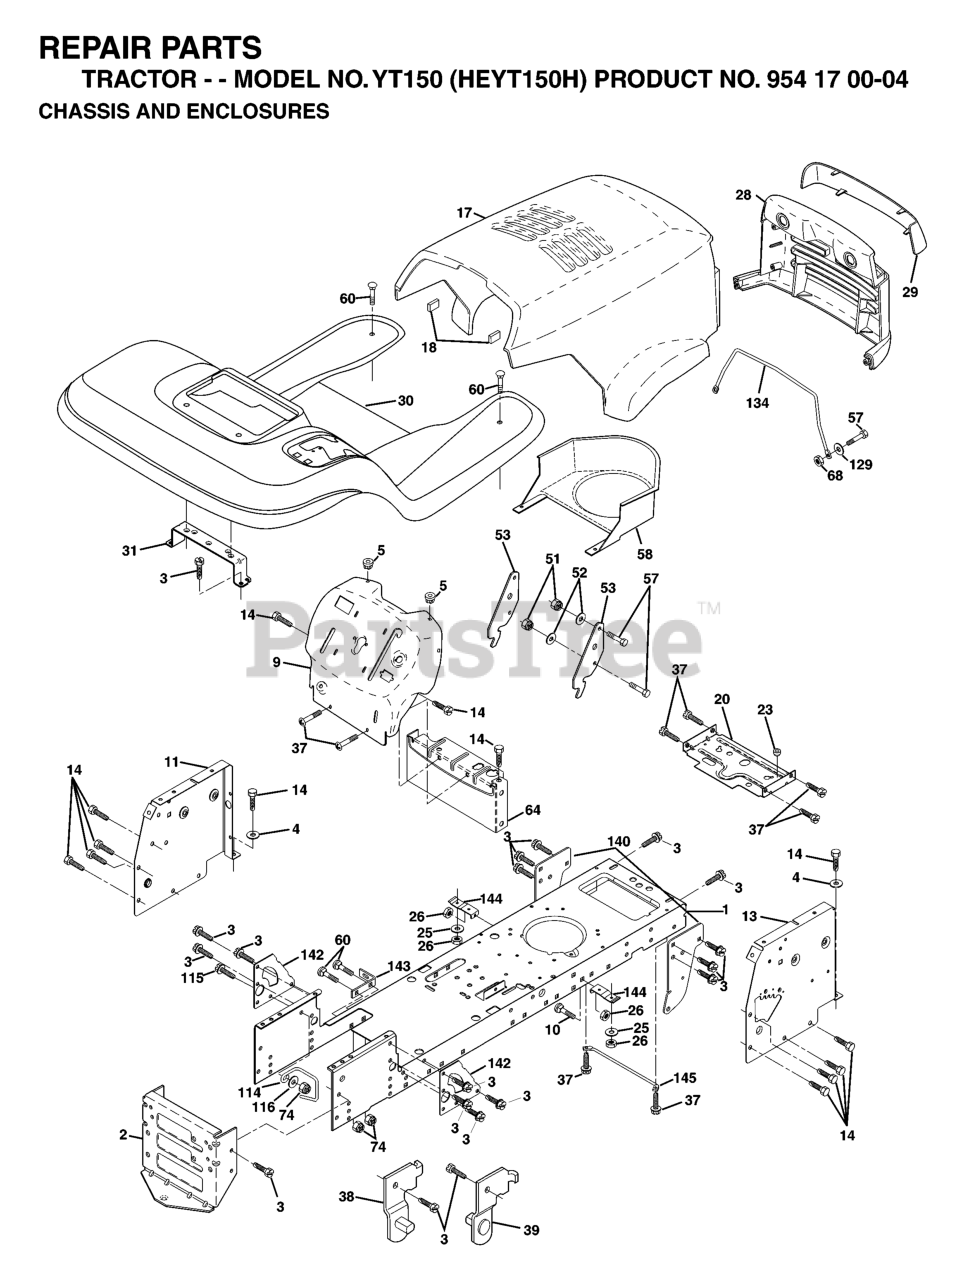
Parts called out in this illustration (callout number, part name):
2	STRETCH DRAWBAR
3	SCREW
4	Washer 13/32 X 3/4 X 16 Ga.
5	BUMPER.RUBBER.HOOD
10	BOLT D
11	PANEL DASH LH
13	DASH PANEL
17	HOOD - LT/YT
18	BUMPER HOOD T
20	PLATE MTG
23	BUSHING.SNAP.NYL.BLK.
25	WASHER
26	NUT
28	GRILLE LT/PL HUSQVARNA
29	LENS LT/PL HUSQVARNA
30	FENDER FOOTREST
31	BRACKET.SUPPORT.FENDER
37	Screw 5/16-18 x 1/2 Hex, Self Tapping 5/16-18 x 1/2
38	BRACKET LH PIVOT
39	BRACKET RH PIVOT
51	LOCKNUT.NYLOC.1/4-20
53	BRACKET PNT PICK OFF LT/PL
57	BOLT
58	AIR DUCT P/L/LT
60	Bolt - Rd. Hd. Sq. Neckiage 3/8 16 x 3/4
64	DASH LOWER
68	NUT
114	BELT GUIDE
115	SCREW
122	WASHER
134	ROD SUPPORT HOOD LT/PL HUS.
140	BRACKET SUSPENSION FRONT
142	PLATE REINFORCEMENT
143	BRACKET, SWAY BAR
144	BRACKET FOOTREST
145	ROD PIVOT CHASSIS/HOOD
